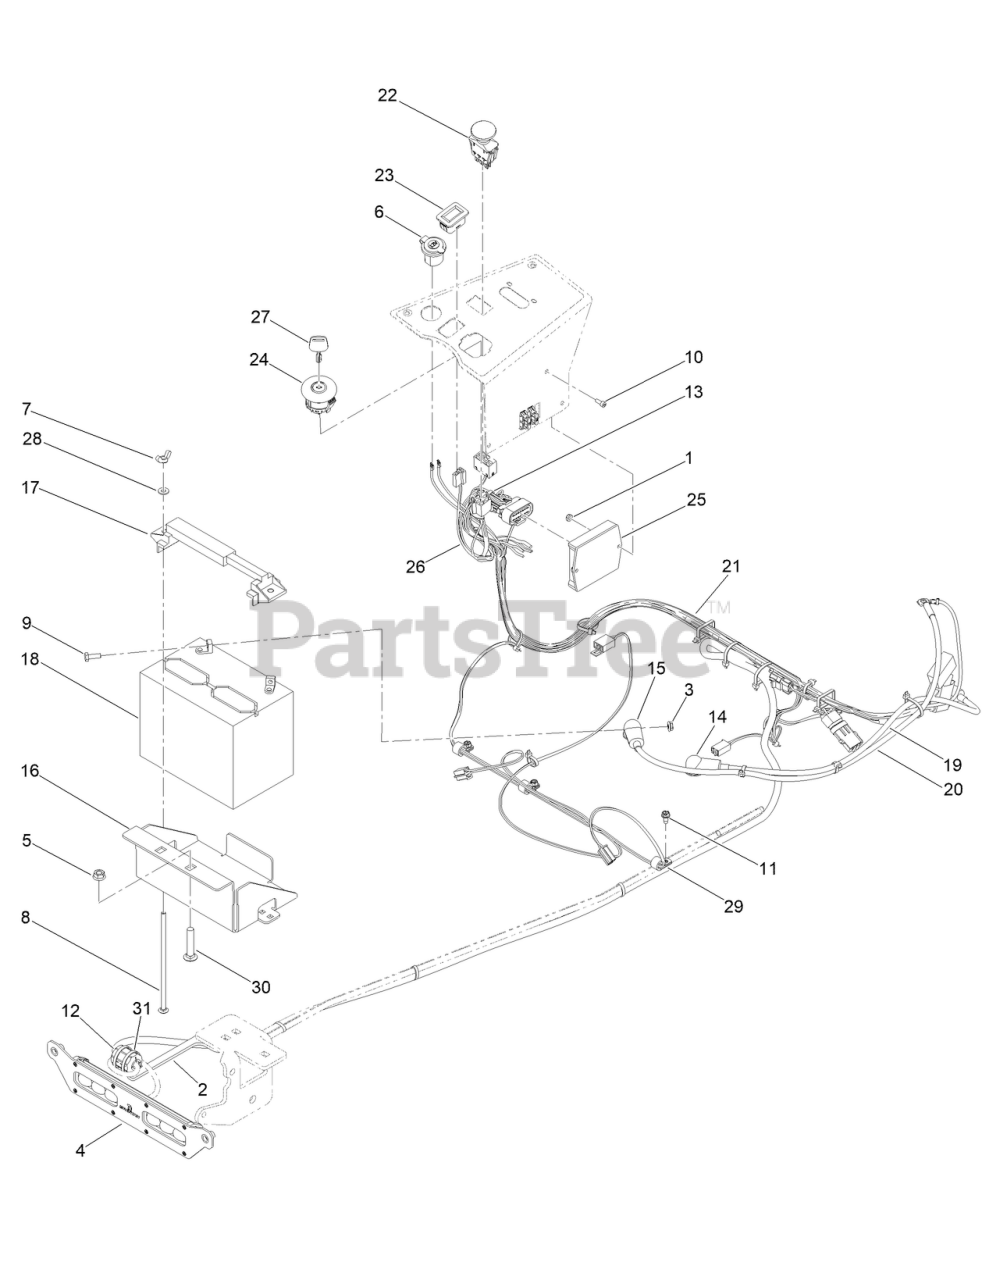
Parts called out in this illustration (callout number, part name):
1	NUT-LOCK
2	FAIR-RITE BRACKET PAINTED
3	1/4-20 HEX FLANGE NUT
4	SPLIT BEAM W/NON-LIGHTD HELMET LIGHT BAR
5	3/8-16 HEX FLANGE NUT W/SERR ZINC YELLOW
6	12 VOLT AUXILLIARY PLUG
7	NUT-WING
8	1/4-20 X 7 CARRIAGE BOLT ZINC
9	SCREW-HH
10	10-24 X 1/2 SOCKET C/S 18-8 SS
11	SCREW-HWH
12	FAIR-RITE ROUND CABLE SNAP-IT SIZE B
13	6IN (40 LB) CABLE TIE NYLON UV
14	3.15 LGTH STRAIGHT INSUL TERM COVER RED
15	STRAIGHT INSULATING TERMINAL COVER
16	MWR BATTERY BOX
17	BATTERY HOLD DOWN
18	MWR START BATTERY 350CCA
19	MWR POSITIVE BATTERY CABLE 25IN
20	MWR NEGATIVE CABLE 28
21	HARNESSVANGUARD 26HP + KAWI 852CC/999CC
22	PTO SWITCH
23	HOUR METER
24	IGNITION SWITCH
25	INTERLOCK MODULE
26	MWR KEYSWITCH JUMPER HARNESS
27	2023 MWR KEY
28	WASHER-FLAT
29	CLAMP-R
30	SCREW-CARR
31	TIE-CABLE
